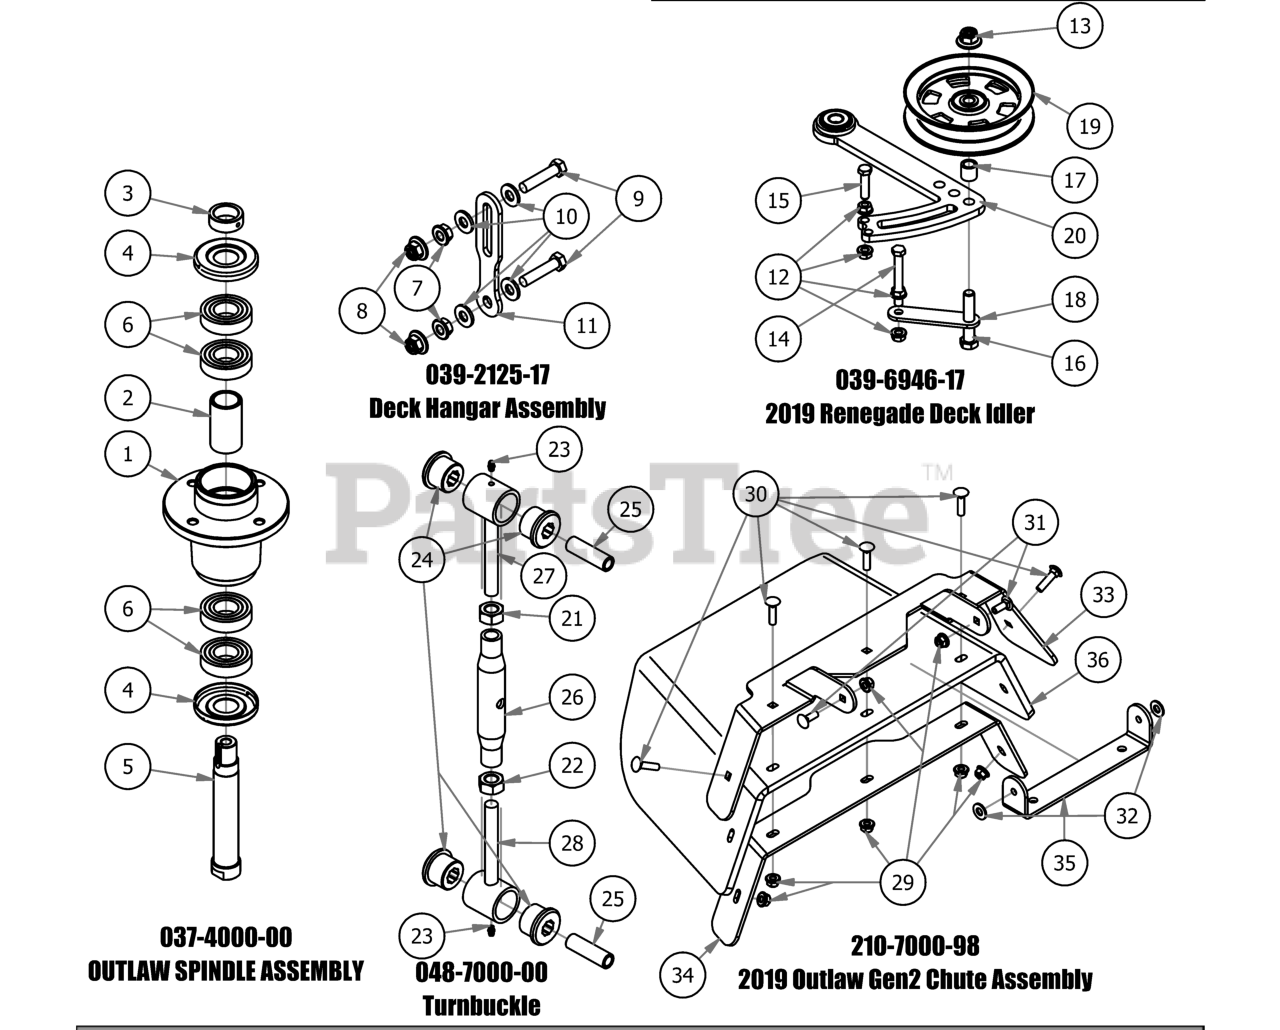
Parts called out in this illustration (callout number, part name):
1	4000 Series Spindle Housing
2	4000 Series Spindle Spacer
3	Locking Collar w/ 1/4"-20 Set Screw
4	Spindle Dust Cap
5	Spindle Shaft
6	Bearing - 6206
7	1/2" Flange Nut
8	1/2-13 NYLON INSERT FLANGE LOCKNUT ZINC
9	1/2-13X 2-1/4 GR Hex Bolts
10	.505 Nylon Spacer
11	Deck_Hanging_Tab
12	3/8" Flange Nut
13	1/2-13 NYLON INSERT FLANGE LOCKNUT ZINC
14	3/8-16x3 grade 5 hex bolt
15	3/8 x 1.5" Bolt
16	1/2" x 2 3/4" Hex Bolt
17	Spacer 3/4 OD x 1/2 ID x 3\4 Length
18	Belt Tensioner Retainer Plate
19	5" Idler Pully
20	2019 Deck Tensioner
21	Hex Nut, 11/16-12
22	Hex Nut, 11/16-12 Left Handed
23	1/4" Press in Grease Fitting
24	Polyeurethane Bushing
26	2015 Outlaw Toplink Body
27	Right-Handed End
28	2015 Outlaw Toplink LH End
29	5/16" Nylon Flange Nut
30	5/16" x 1 1/4" Carriage Bolt
31	5/16" x 7/8" Carriage Bolt
32	.360 ID Plastic Washer
33	2019 Upper Chute Bracket
34	2019 Lower Chute Bracket
35	2019 Chute Hanger
36	2019 Belted Chute with Logo
